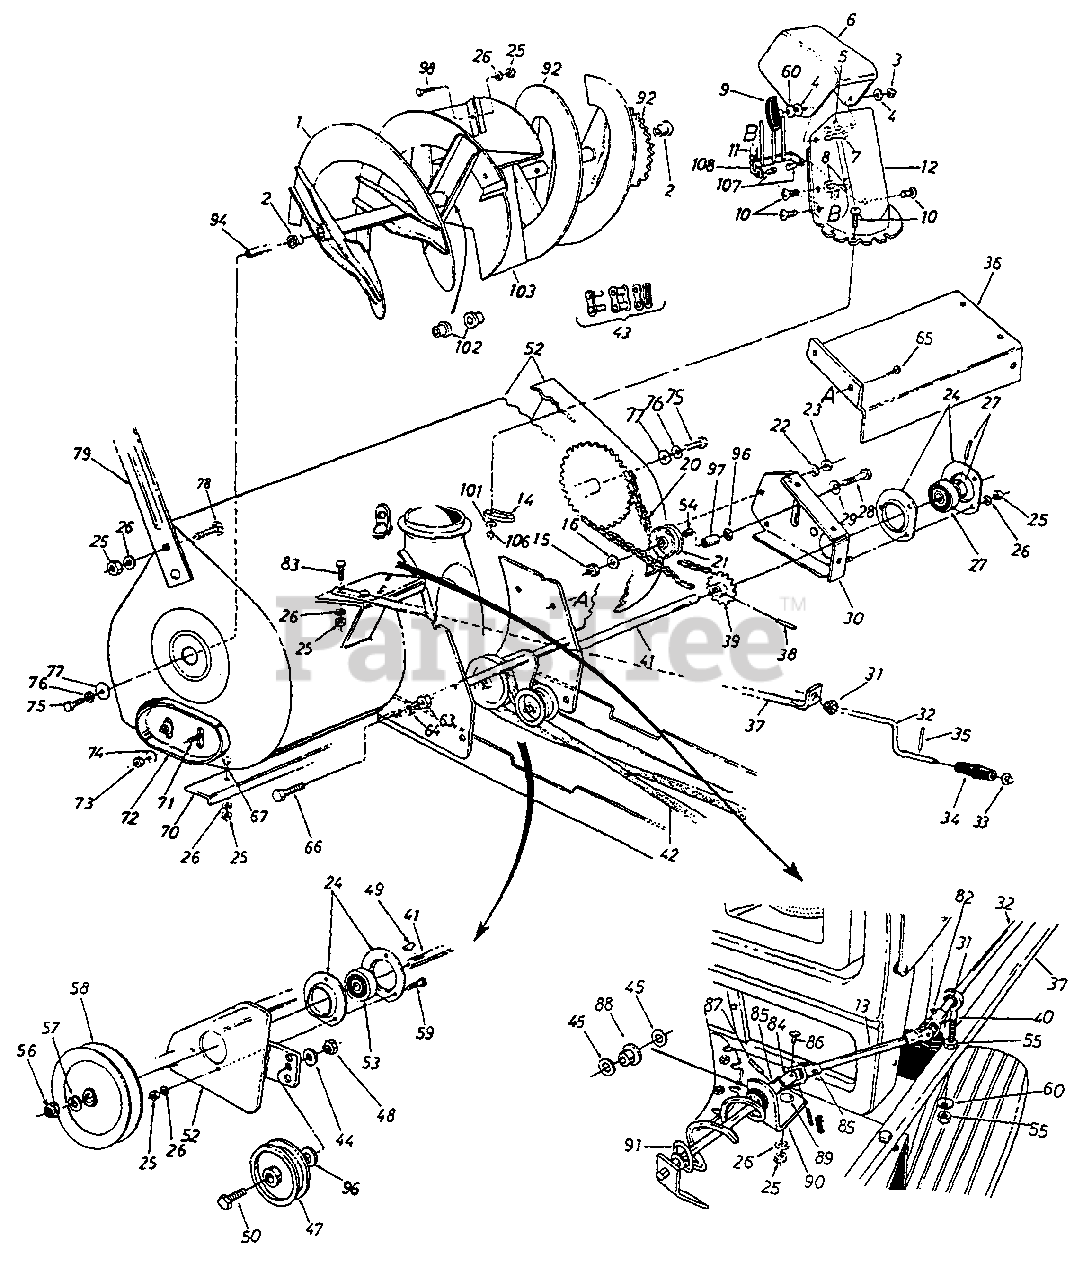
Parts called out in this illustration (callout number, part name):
3	Hex L-Nut 5/16-18 Thd.
4	Fl-Wash .344" I.D.
5	Truss Mach. Scr. 5/16-18 x .75" Lg.
6	Upper Chute
7	Carriage Bolt 5/16-18 x 1.0" Lg.
8	Hex L-Nut 1/4-20 Thd.
9	Hand Knob
10	Truss Mach. Scr. 1/4-20 x .75" Lg.
11	Ext. Spring
12	Lower Chute
13	Chute Crank Extension Rod
14	Chute Flange Keeper
15	L-Nut 3/8-16 Thd.
16	Fl-Wash.
20	#420 Chain 1/2" Pitch x 77 Links
21	Plastic Idler 2" O.D.
22	L-Wash. 1/4" I.D.
23	Hex Nut 1/4-20 Thd.
24	Bearing Housing
25	Hex Nut 5/16-18 Thd.
26	L-Wash. 5/16" I.D.
27	Self-Aligning Bearing
28	Hex Bolt 3/8-16 x 1.75" Lg.
29	Belleville Wash. 3/8" I.D.
32	Chute Crank .375" Dia. x 34.5" Lg.
33	Push Nut 3/8" Rod
34	Knob (Black)
35	Roll Pin
39	14 Teeth Sprocket Ass'y.
40	Eyebolt 5/16-18 x 3.0" Lg.
41	Drive Shaft
42	"V"-Belt
43	Master Link for #420 Chain
44	L-Wash. 3/8" I.D.
45	Fl-Wash .385" I.D. x .62" O.D.
47	Fl-Idler with Flanges
48	Hex Jam L-Nut 3/8-16 Thd.
49	#61 Hi-Pro Key 3/16 x 5/8 Dia.
50	Hex Bolt 3/8-16 x 1.75" Lg.
52	Spiral Housing Ass'y.
53	Self-Aligning Bearing
54	Sleeve Bearing .50" i.D.
55	Hex Nut 5/16-18 Thd.
56	Hex Nut 3/4-10 Thd.
57	L-Wash. 3/4" I.D.
58	"V"-Pulley.750" I.D. x 6" D.D.
59	Hex Sems Bolt 5/16-18 x .75" Lg.
60	Bell-Wash .345" I.D. x.88" O.D.
65	Hex Self-Tap Scr. 1/4-20 x .5" Lg.
66	Hex Bolt 1/2-20 x 1.25" Lg.
67	Carriage Bolt 5/16-18 x .75"
73	Hex Jam Nut 3/8-16 Thd.
74	Bellevilie Wash. 3/8" I.D.
75	Hex Bolt 1/2-13 x 1.25" Lg.
76	Belleville Wash. 1/2" I.D.
77	Fl-Wash.
78	Carriage Bolt 5/16-19 x .62" Lg.
82	Cotter Pin
83	Hex Bolt 5/16-18 x 1.5" Lg.
84	Joint Block
85	Joint Bracket Ass'y.
86	Oval Head Rivet
87	Spring Pin Roll 1/8" Dia, x .75" Lg.
88	Nylon Bushing
89	Carriage Bolt 5/16-18 x .75" Lg.
90	Chute Crank Bracket
91	Chute Crank Ass'y.
96	Flat Washer
97	Idler Spacer
98	Carriage Bolt 5/16-18 x .75" Lg.
101	Fl-Wash. 1/4" I.D.
102	Plastic Bushing
107	Shld. Nut 1/4-20 Thd.
05139A-0637	BLADE-GUIDE (DRIFT - POWDER BLACK (0637)
05139A-0638	BLADE-GUIDE (DRIFT - MTD/TROY-BILT RED (0638)
05139A-0662	BLADE-GUIDE (DRIFT - OYSTER GRAY (0662)
05139A-0665	BLADE-GUIDE (DRIFT - YARDMAN GREEN (0665)
05139A-0674	BLADE-GUIDE (DRIFT - YARDMAN YELLOW (0674)
05139A-0716	BLADE-GUIDE (DRIFT - CUB YELLOW-99 (0716)
